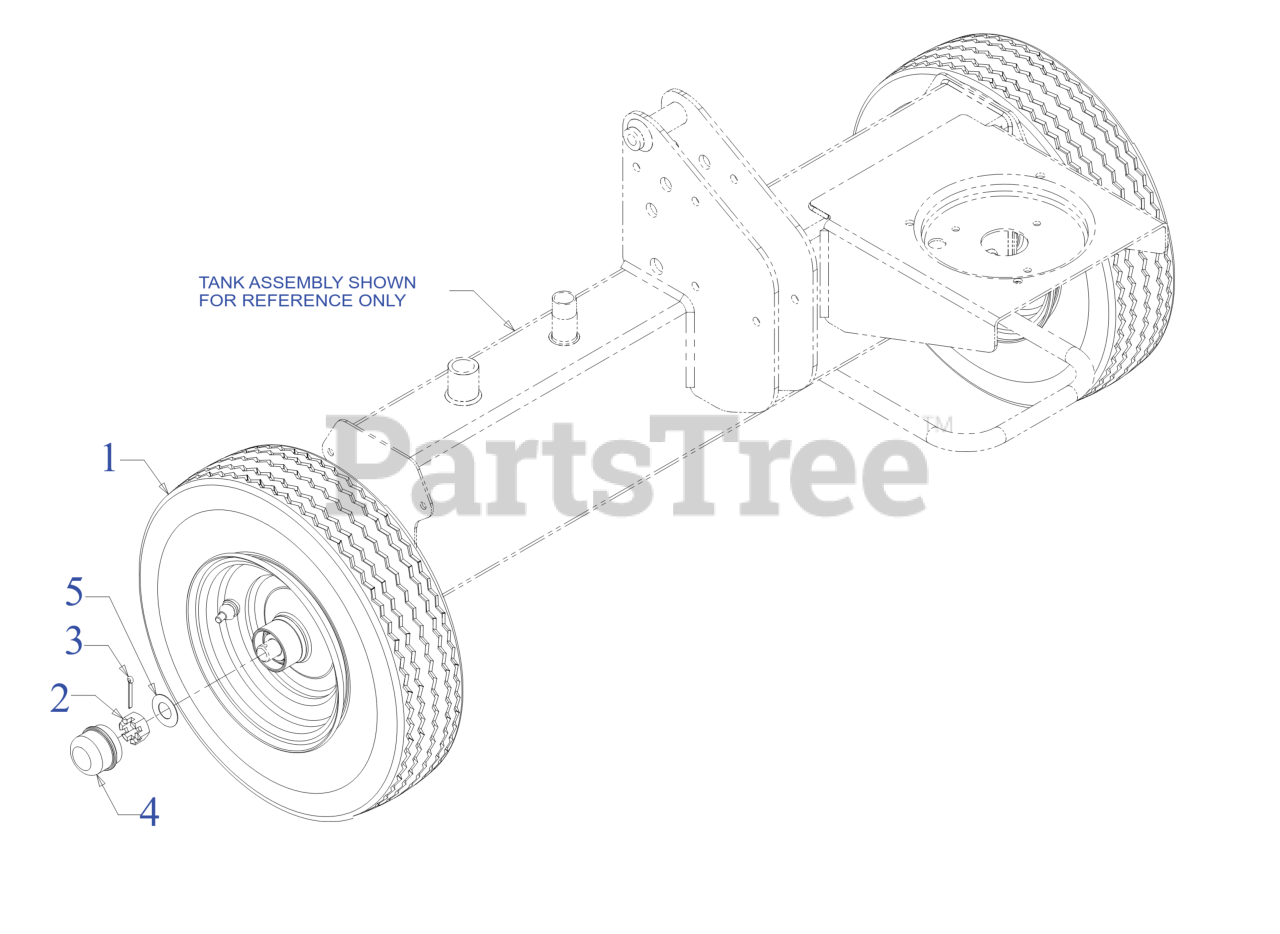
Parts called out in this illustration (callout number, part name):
1	WHEEL ASSEMBLY (CRAFTSMAN GREY)
2	HEX NUT CASTLE 3/4-16
3	COTTER PIN-5/32 DIA
4	HUB CAP
5	THRUST WASHER
